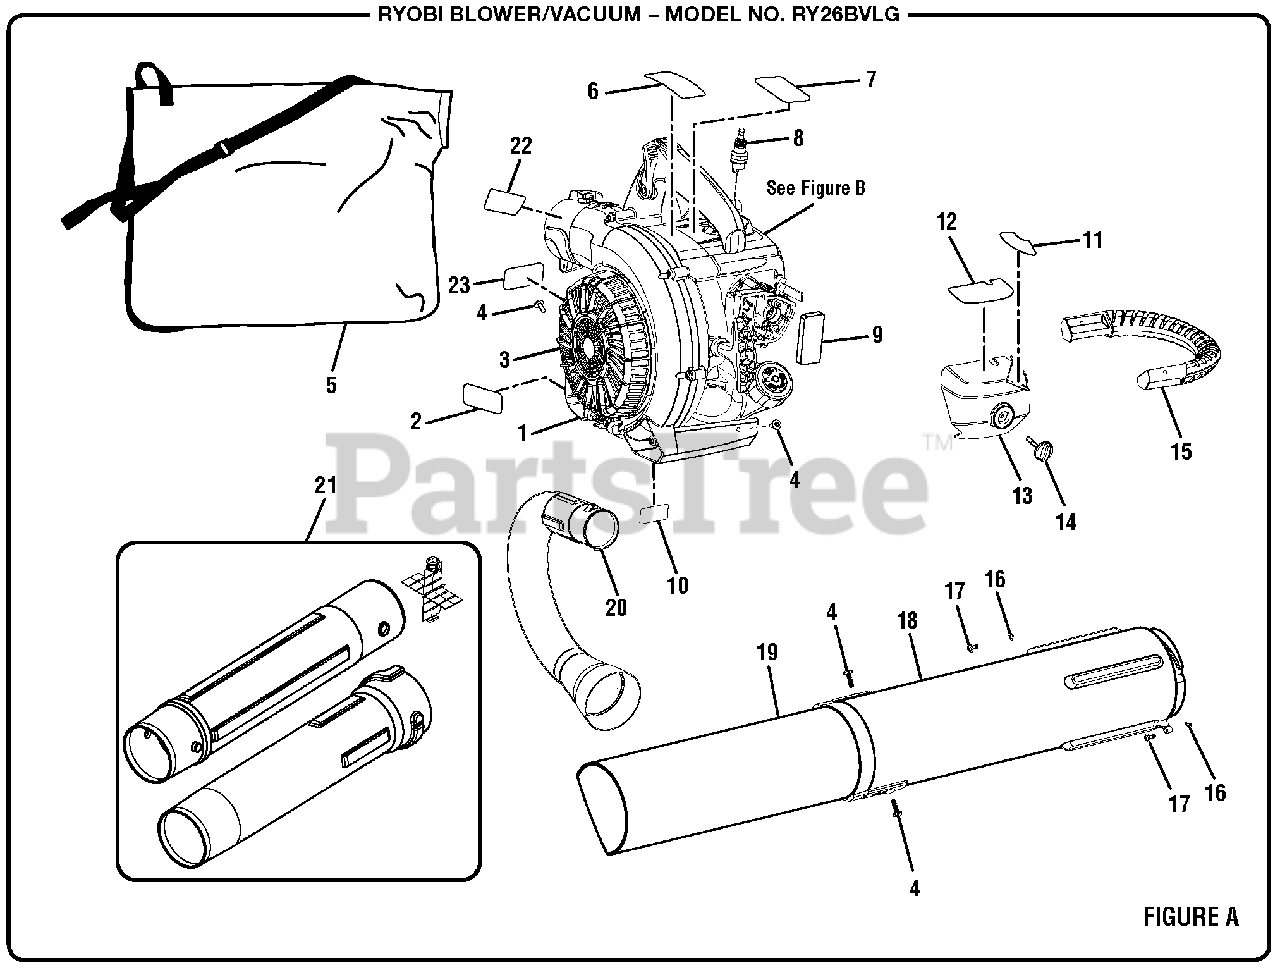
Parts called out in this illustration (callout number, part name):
1	Vacuum Door Spring
2	Combustion Label
3	Vacuum Door
4	Vacuum Tube Screw (10-14 x 1/2 in.)
5	Vacuum Bag w/Shoulder Strap
6	Warning Label
7	Logo Label (Small)
8	Spark Plug (L7RTC)
10	EMC Label (UT26HBVEMC only)
11	Choke Label
12	Starting Label
13	Air Filter Cover
15	Vacuum Handle
17	Screw (1/4-20 x 3/4 in.)
18	Upper Vacuum Tube
19	Lower Vacuum Tube
20	Vacuum Bag Adaptor
21	Blower Tube Assembly
22	Tube Removal Label
23	Hot Surface Label
